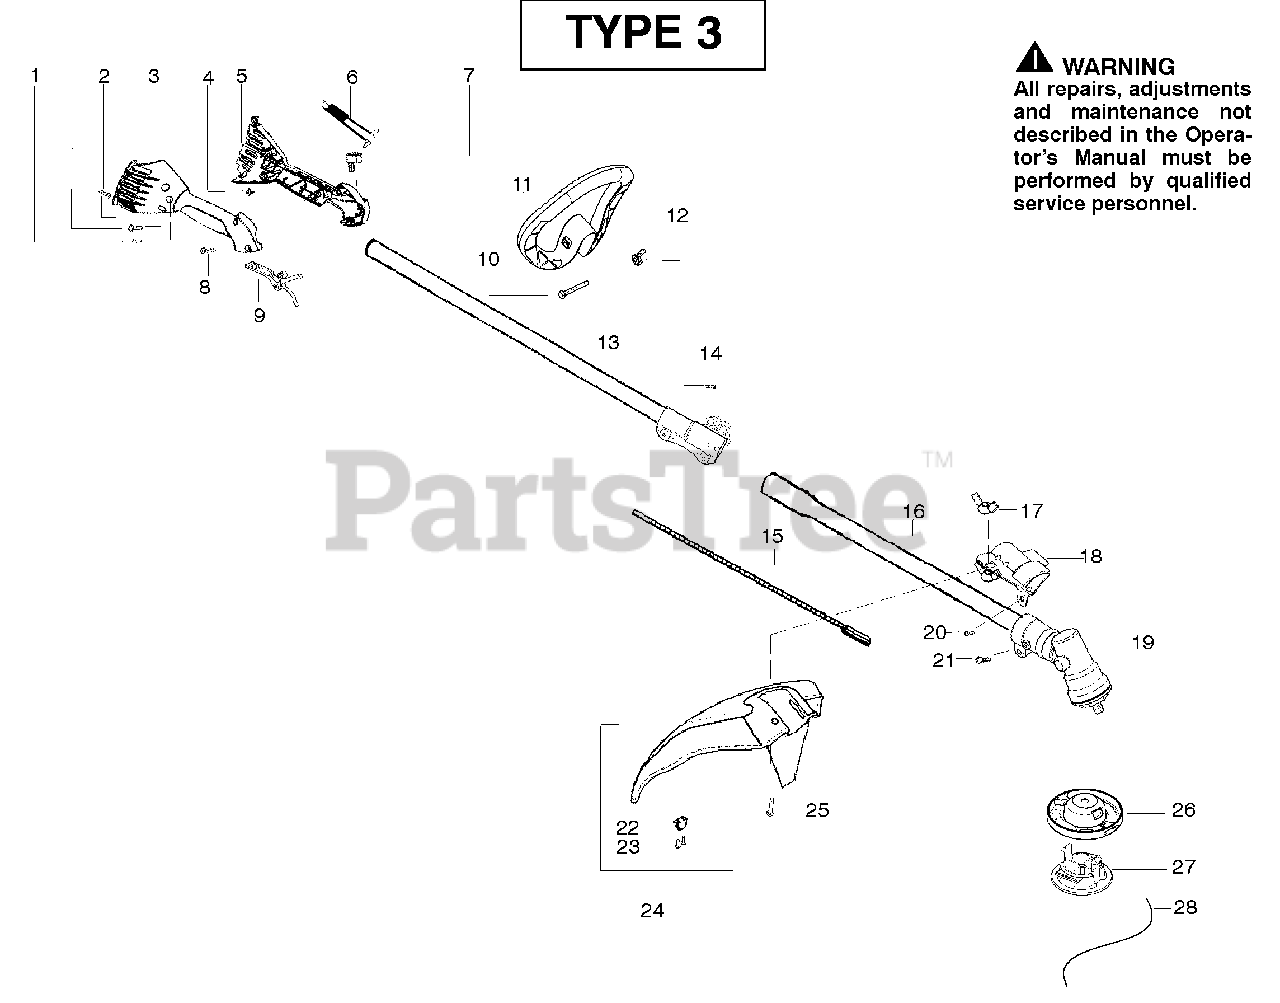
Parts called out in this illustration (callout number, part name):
1	Screw-alignment
3	Hsg.-Throttle right
4	Screw-Cable Retention
5	Hsg.-Left throttle
9	Lever-Throttle
11	Assy-Handle
12	Wingnut
13	Kit-Upper Shaft
15	Shaft-Flex (lower)
16	Kit-Lower Shaft
17	Wingnut
18	Bracket-Shield
24	Kit-Shield Assy.
26	Head-Fixed Line
27	Cap-Fixed Line
28	Accy-Line (12 pcs)
